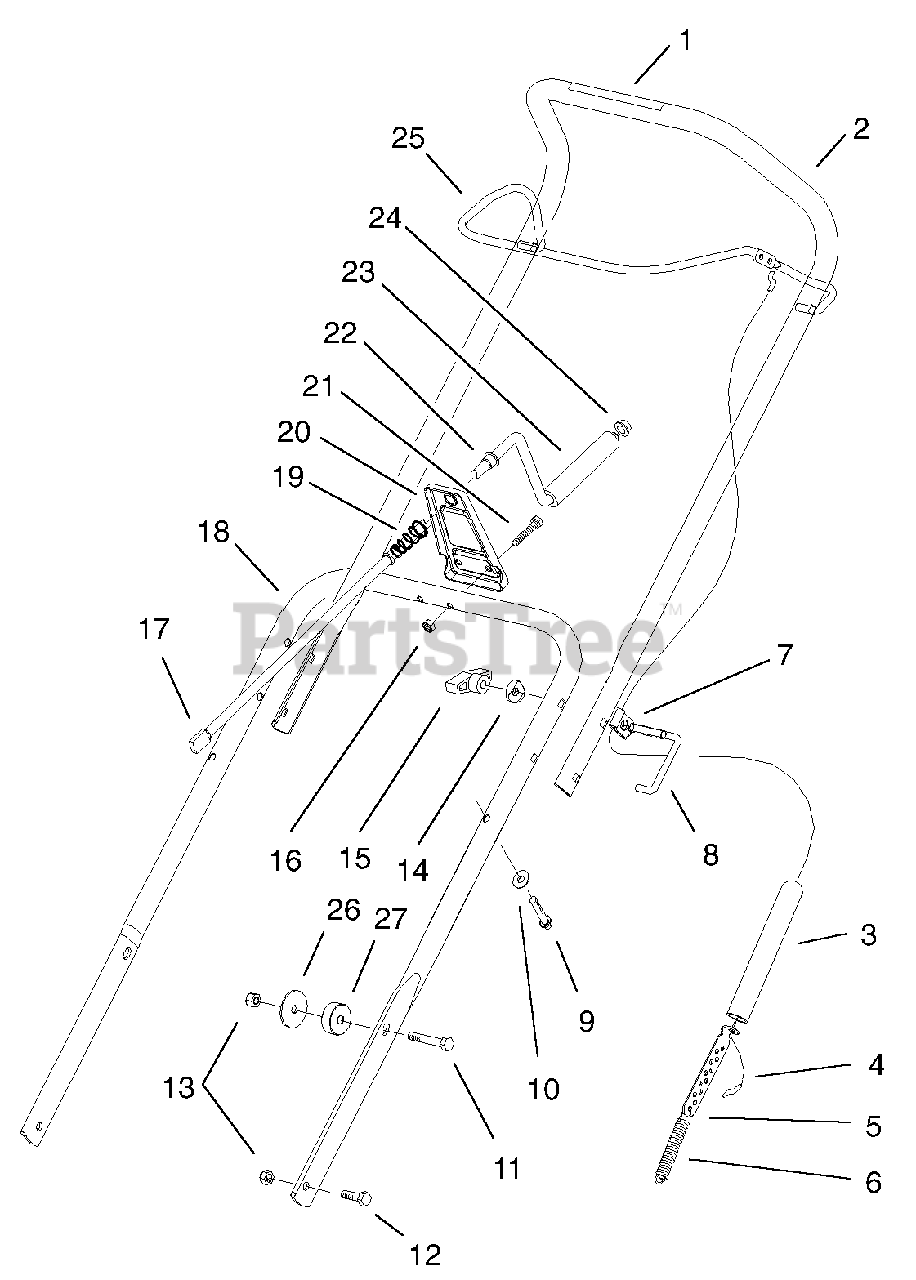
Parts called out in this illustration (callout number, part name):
1	DECAL-DRIVE, ROTOR
2	HANDLE-UPPER W/DECAL ASM
3	COVER-SPRING
4	CABLE-CLUTCH
5	ADJUSTER-CABLE
6	SPRING-EXTENSION
8	LOCK-HANDLE
9	SCREW
11	SCREW-HH
12	SCREW-HH
13	NUT-LOCK, NI
14	WASHER-CURVED
15	KNOB-HANDLE
16	NUT-LOCK, NI
17	ROD-CRANK, CHUTE
18	HANDLE-LOWER
19	SPRING-COMPRESSION
20	SUPPORT-CRANK, CHUTE
21	SCREW-HH
22	Bushing
23	GRIP-CHUTE CONTROL
24	RETAINER-PUSH ON
25	BAIL-CONTROL
26	WASHER-FLAT
